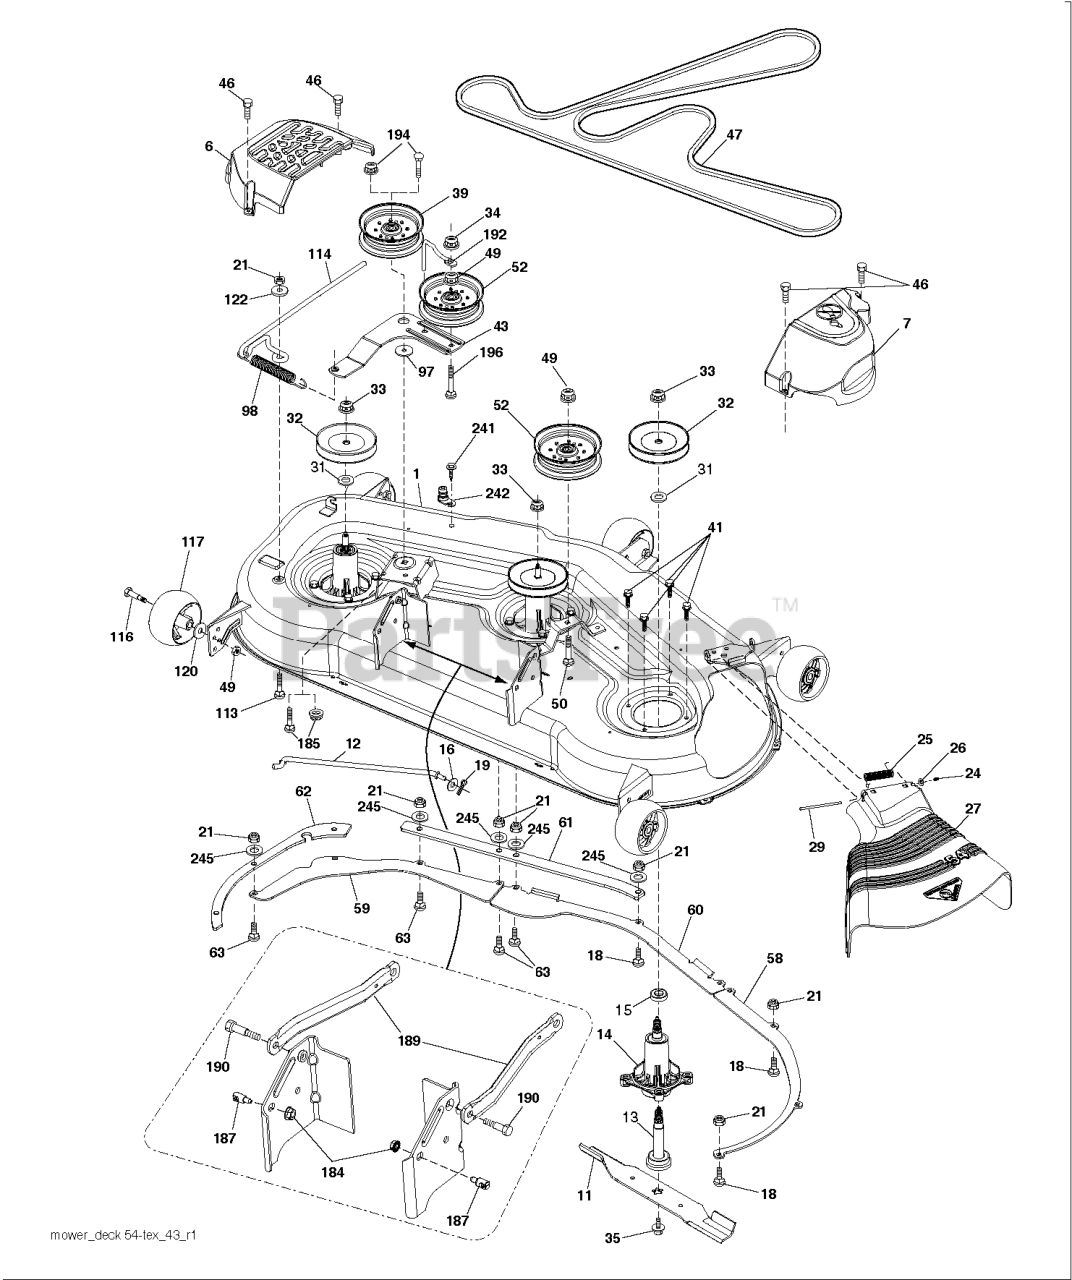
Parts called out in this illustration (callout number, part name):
1	DECK.SVC.54".5GWB.GREY
1	DECK SVC 54" 417743X668
6	COVER.MANDREL.LH.54"20
7	COVER.MANDREL.RH.54.20
11	54" MULCH BLADE
11	BLADE.BAGGING.54"
12	ROD.ANTI.SWAY.48/54"K4
13	SHAFT ASSY, MANDREL SHAFT
13	SHAFT ASM MANDREL
14	KIT.MANDREL.GREASEABLE.TALL
14	KIT.MANDREL.NONGREASE.TALL
15	BEARING.MANDREL.TOP.EXTENDED
15	BEARING
16	GSPH
18	BOLT
18	BOLT ROUND HEAD SQUARE NECK BO
19	PIN.COTTER.5/16.BOW TI
24	CAP-SLEEVE LT
25	SPRING, TORSION
26	NUT PUSH M
27	DEFLECTOR
31	WASHER.SPACER.MANDREL
32	PULLEY/MANDREL
35	SCREW.SEMS.7/16-20X1.HEX.HEAD
35	BOLT.WASHER.ASM.7/16-2
39	RB PULLEY.IDLER.4.50/HUB SPEC
41	BOLT.HEX.WASHR.HED.313-18X1.19
46	SCREW.1/4-20X5/8
47	BELT.DECK.DRIVE.BELT.54
49	NUT LOCK FLG 3/8-16 UNC
52	PULLEY.IDLER.2006
58	BAFFLE.RIGHT.54"
59	BAFFLE.LEFT.54"
60	BAFFLE CENTER 54" MOWER
61	PLATE.REIN.FRONT.BOLT54"X431
62	PLATE.REIN.SIDE.BOLT.54"X431
63	BOLT
63	BOLT.CARRIAGE.5/16-18
98	SPRING, DECK DRIVE
113	BOLT CRT
114	ROD TENSION RELIEF
117	WHEEL.GAUGE.RALLY
122	BUSHING.RELIEF.TENSION
184	NUT LOCK HEX FLANGE 5/16-18
185	NUT.LOCK.FLANGE.7/16
187	STUD.W/"D"ANTI-ROTATION
189	ARM.SUSPENSION.MOWER
189	LINK.ASM.LIFT.REAR
189	ARM.RFIXED.MOWER.SUSPNSIONX431
190	BOLT.SHOULDER
192	KEEPER.BELT.IDLER.54"T
194	BOLT.HEX.WASHER.HEAD.7/16-24X
196	BOLT
241	SCREW.TT.#10-32X.5.3/8.FLANGE
242	PORT.WASHOUT
245	WASHER 11/32 X 11/16 X 14 GA T
